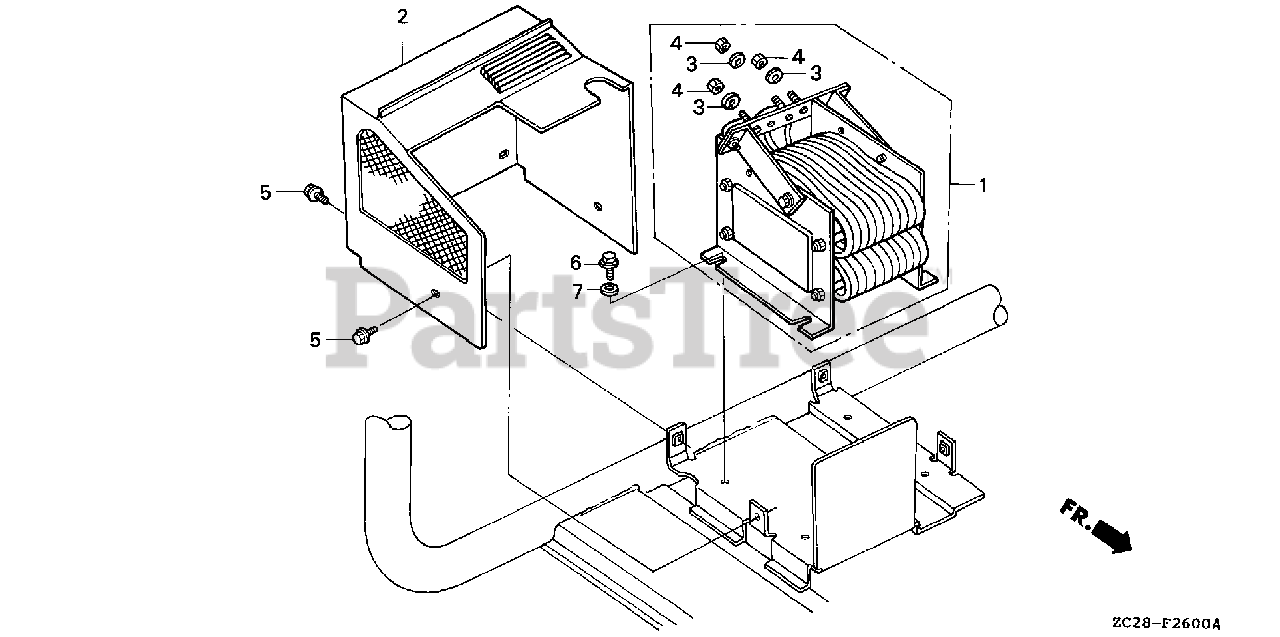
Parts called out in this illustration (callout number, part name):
1	REACTOR ASSY.
2	COVER, REACTOR
3	WASHER, SPRING (6MM)
4	NUT, HEX. (6MM)
5	BOLT, FLANGE (6X10)
6	BOLT, FLANGE (8X16)
